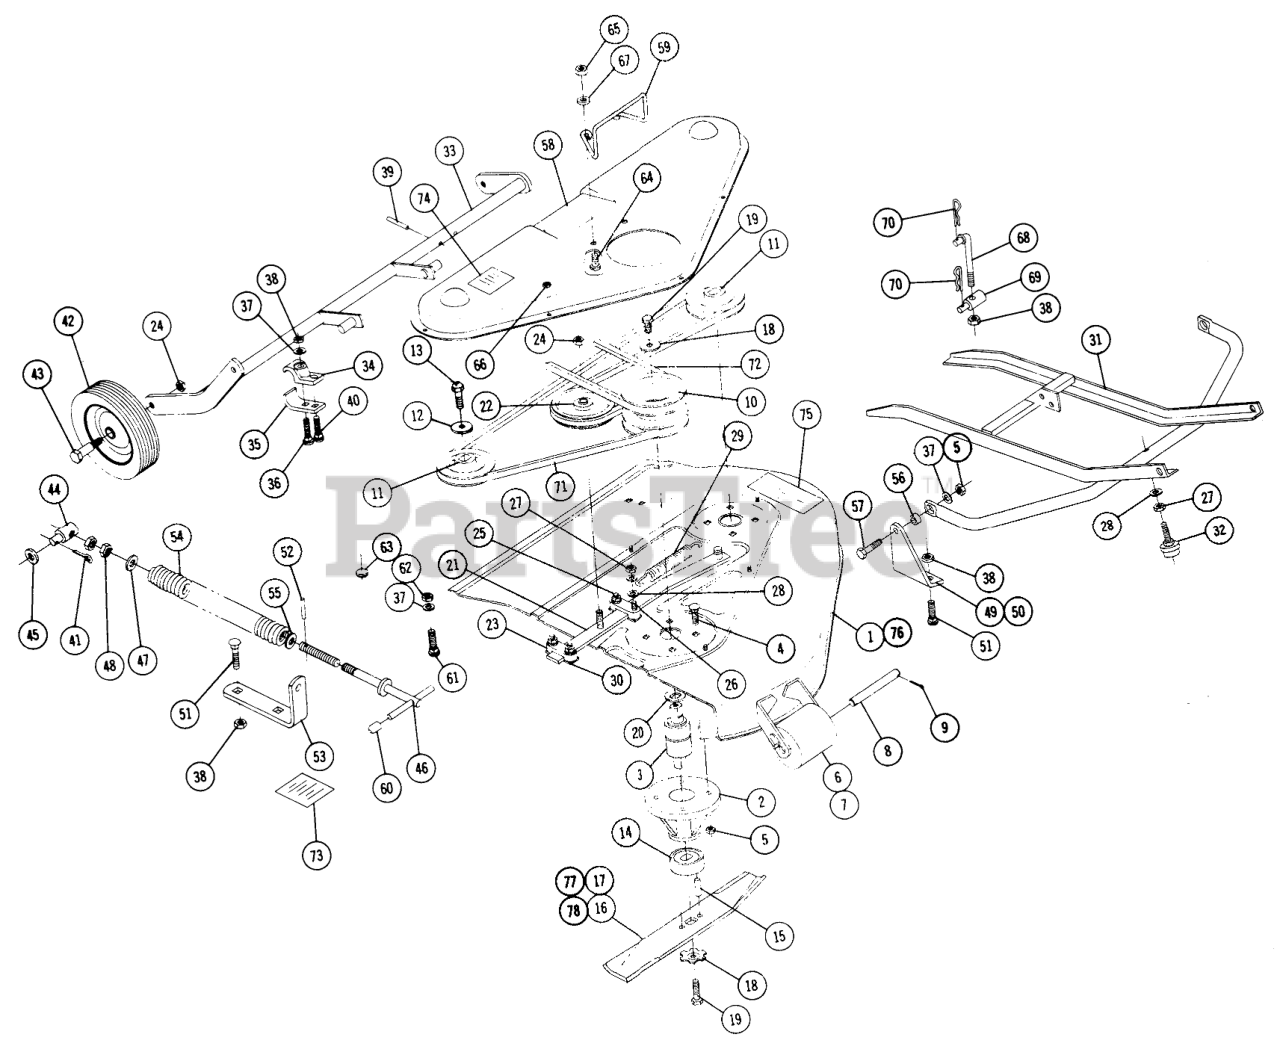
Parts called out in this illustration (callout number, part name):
1	Deck-Mower (Model 5-0610)
2	Housing
3	Bearing-Spindle
4	Bolt Carriage 3/8-16 x 1
6	Roller
7	Bearing-Nylon
8	Shaft
9	Cotter Pin
10	Pulley
11	Pulley
12	WASHER
13	Bolt 3/8-16 x 3/4 Hex
14	Cup-Spindle
15	SPIROL ROLL PIN
16	Blade 14"
17	Blade 12"
18	WASHER
19	Bolt 3/8-16 x 7/8
20	WASHER
21	Bar Idler Support
22	Idler Pulley
23	Side Block
24	3/8-16 Jam Nut
25	Bolt-5/16-18 x 1/4
26	Bolt-5/16-18 x 1 1/2
27	Nut-Nylok
28	Washer
29	SPRING R
30	SLIDE
31	Mower Lift
32	LEVELER MOWER
33	Height Control Bracket
34	Support
35	Clip
36	Bolt-Carriage
37	Washer
38	3/8-16 E.S.
39	Roll Pin
40	Bolt Carriage 3/8-16 x 1
41	Hairpin
42	Wheel
43	BOLT-SHOULDER
44	ROD-TRUNNION LIFT
45	Spacer
46	Crank
47	Washer
48	Nut-1/2-13
49	Bracket L.H.
50	Bracket R.H.
51	Bolt 3/8-16 x 1
52	PIN-SPIROL
53	Bracket
54	Spring
55	Washer Teflon
56	SPACER
57	Bolt 3/8-16 x 1
58	Cover
59	BELT GUIDE
60	Cap
61	Bolt 5/16-18 x 5/8 Carriage
62	Nut, 5/16-18
63	Plug Button
64	Screw 1/4-20 x 5/8
65	Nut, 1/4-20
66	HEX NUT 10-32 E.S.
67	Washer
68	Link-Lift
69	Trunnion
70	Hairpin
71	V-BELT
72	BELT DRIVE
73	Decal-Height Adjustment
74	Decal-Belt Installation
75	Decal
76	Deck-Mower (Model 5-0701)
77	Blade 14"-Center (Model 5-0701)
78	Blade 12" (Model 5-0701)
